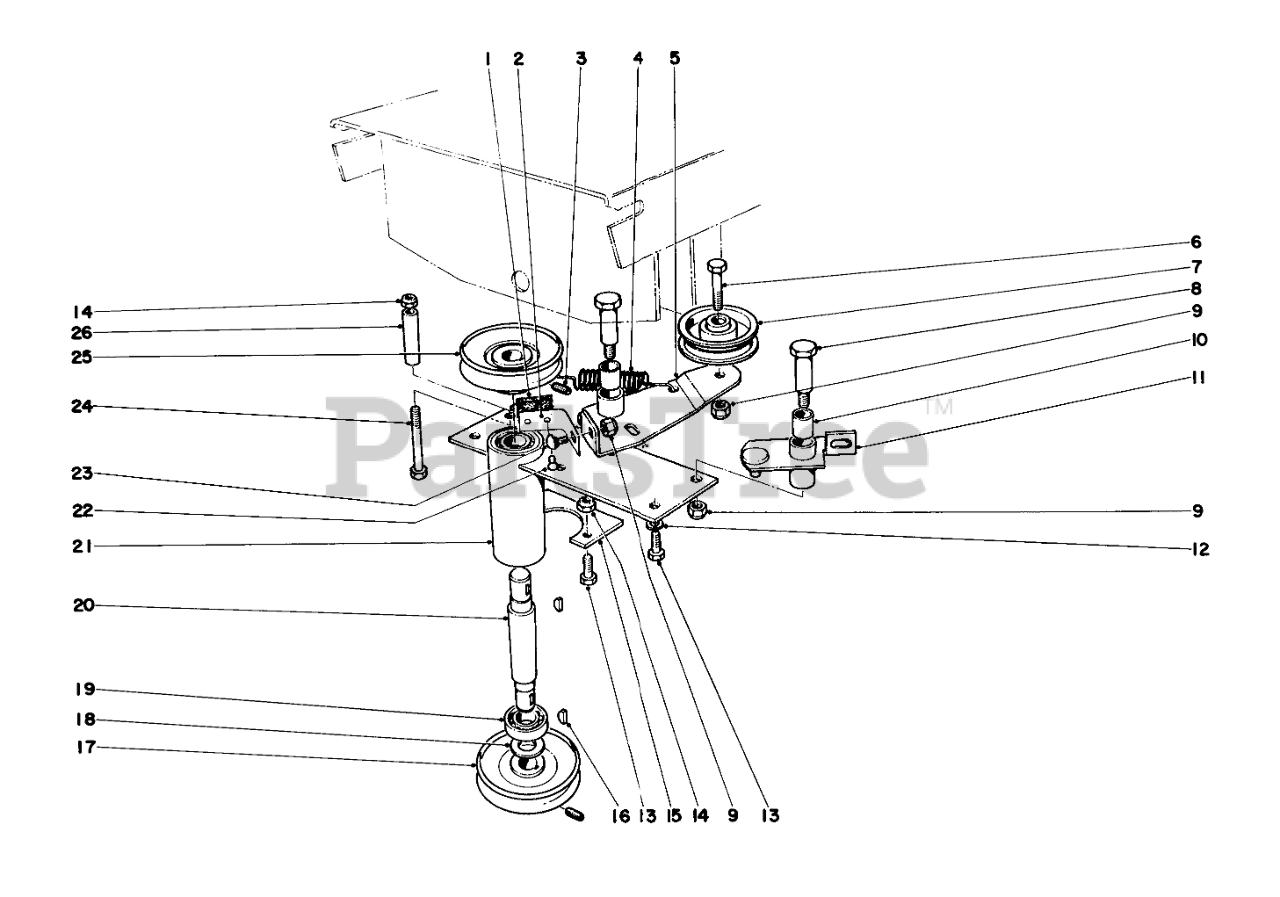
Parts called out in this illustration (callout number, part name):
1	BLADE BRAKE LINING
2	Brake Spring
3	SCREW-SET
4	Spring
5	Idler Plate
6	SCREW-HH
7	PULLEY-IDLER
8	Axle Bolt
9	NUT-LOCK, CONE
10	BUSHING
11	Pivot Bracket (Incl. Ref. #10)
12	WASHER-LOCK
13	SCREW-HH
14	NUT-LOCK, CONE
15	Retainer P.T.0. Tube
16	KEY-WOODRUFF
17	Pulley
18	Bearing Washer
19	Bearing
20	Shaft
21	P.T.0. Tube
22	Rivet
23	SCREW-CARR
24	SCREW-HH
25	Pulley
26	Spacer
